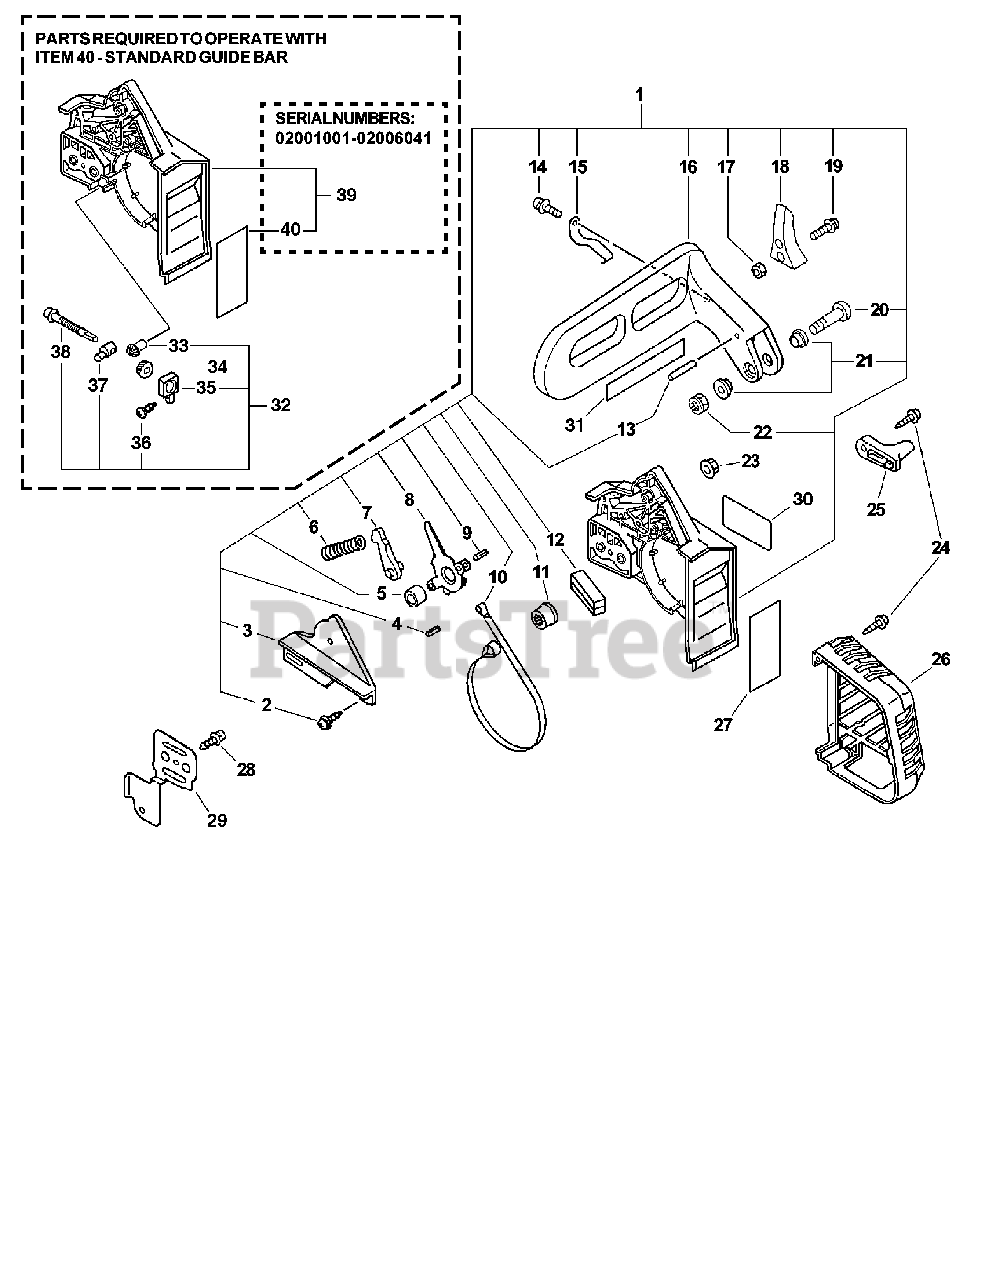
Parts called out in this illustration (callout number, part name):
1	CHAIN BRAKE ASSY
2	SCREW 4×12
3	COVER, BRAKE
4	PIN, SPRING 2.5×12
5	SPACER 8×12×9
6	SPRING, COMPRESSION
7	STOPPER, BRAKE
8	LEVER, BRAKE
9	PIN, SPRING 4×8.8
10	BAND, BRAKE
11	ADJUSTER, BRAKE
12	SEAL, BRAKE
13	ROLLER 4×23.8
14	SCREW 4×10
15	SPRING, FLAT
16	LEVER, BRAKE
18	WEIGHT, BRAKE
19	SCREW 4×20
20	SCREW 5×32
21	COLLAR 5.3×10×13×L5
22	NUT, LOCK M5
23	NUT, FLANGE M6
24	SCREW, TAPPING 5×20
25	CHAIN CATCHER
26	COVER, EXHAUST
27	SHIELD, HEAT 35×60×0.10
28	SCREW 4×10
29	PLATE, GUIDE
30	LABEL, MODEL
31	LABEL, BAR & CHAIN
31	LABEL - BAR & CHAIN
32	SIDE ADJUSTER KIT
33	GEAR, BEVEL
34	GEAR, BEVEL
35	COLLAR 8
36	SCREW 4×12
37	TENSIONER, CHAIN
38	BOLT 5
39	GUARD, SPROCKET - GRAY
40	SHIELD, HEAT 35×60×0.10
